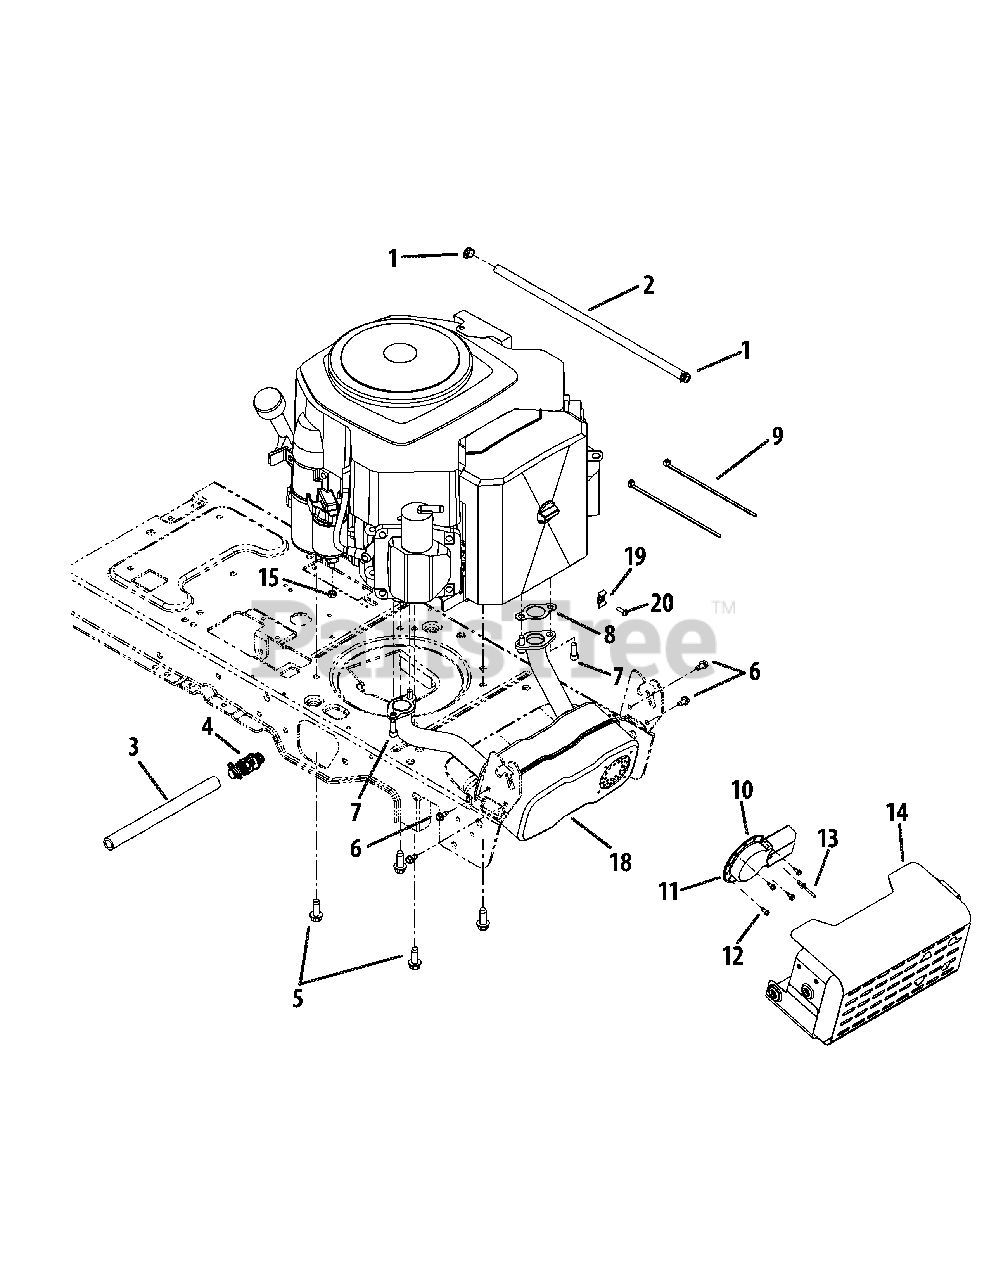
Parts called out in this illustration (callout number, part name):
1	Hose Clamp
2	Fuel Line
3	Oil Drain Hose
4	Oil Drain
5	TT Screw 3/8-16 x 1.00
6	Hex Wash S-Tapp Scr 1/4-20 x .50
7	Scr. 5/16-18 x .75
8	Exhaust Gasket
9	Cable Tie
10	Muffler Deflector
11	Long Muffler Deflector
12	Hex AB Scr #8-18 x .50
13	Pop Rivet
14	Muffler Shield Assembly
18	Muffler
19	Dual Conduit Clamp
20	Tap Screw, M5 x .8
